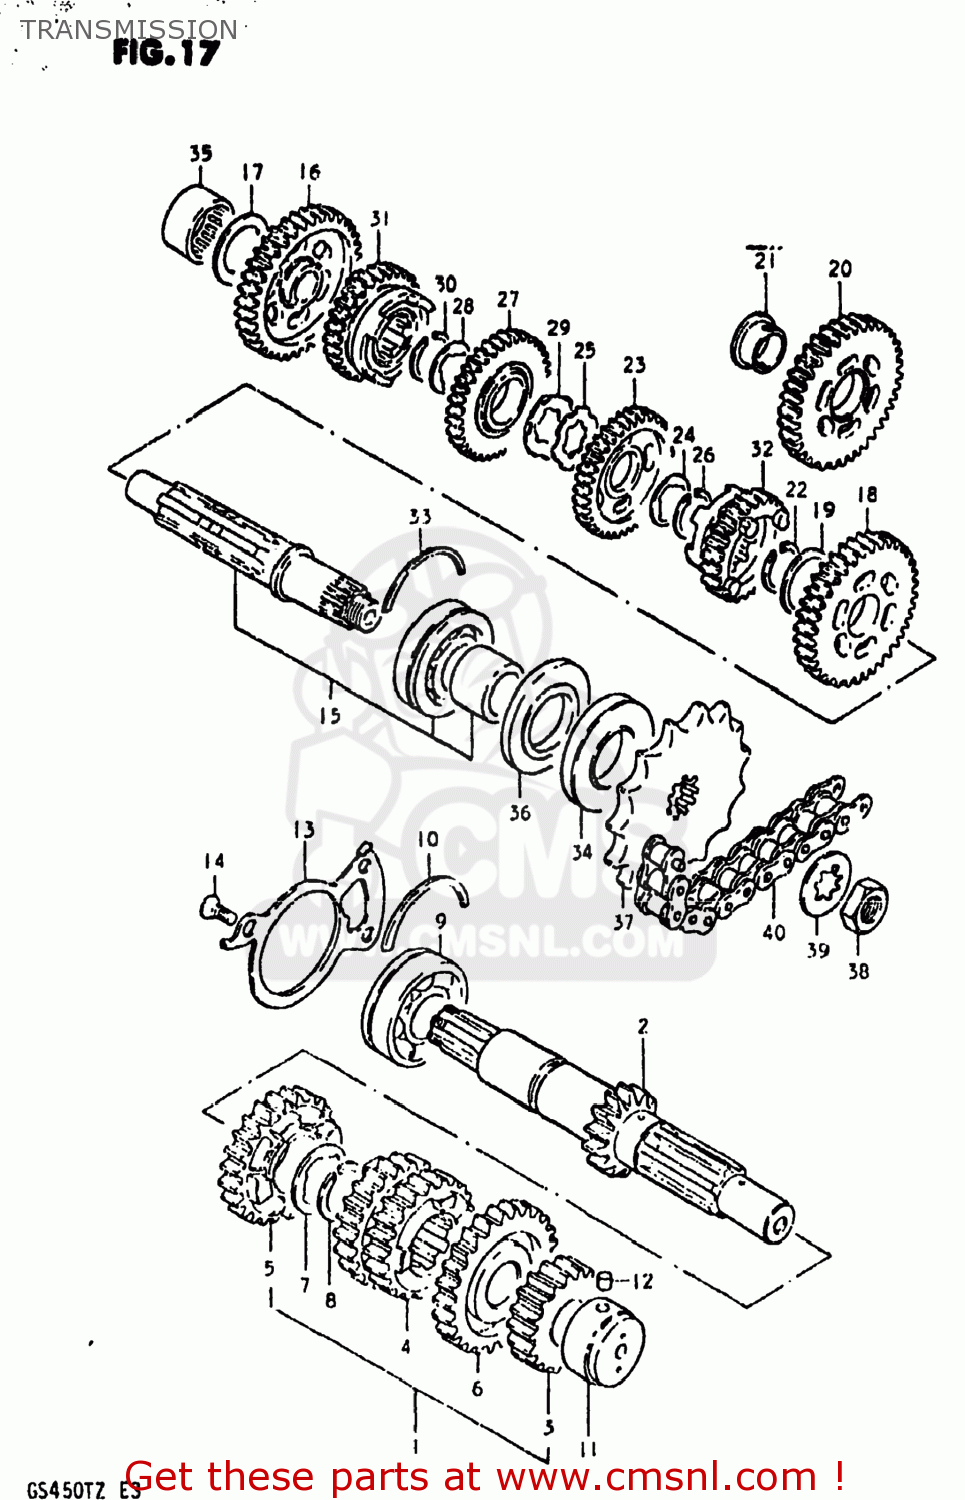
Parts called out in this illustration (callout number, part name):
1	SHAFT,COUNTER
2	SHAFT,COUNTER
3	GEAR,2ND DRIVE(NT:18)
4	GEAR,THIRD DRIVE
5	GEAR,FIFTH DRIVE
6	GEAR,SIXTH DRIVE
7	WASHER
8	CIRCLIP
9	BEARING(25X62X17)
10	C-RING
11	ROLLER BEARING (20X34X2
12	PIN
13	PLATE,COUNTERSHAFT BEARING
14	SCREW
15	SHAFT,DRIVE
16	GEAR,FIRST DRIVEN
17	WASHER
18	GEAR,SECOND DRIVEN
19	WASHER
20	GEAR,SECOND DRIVEN
21	BUSHING
22	CIRCLIP
23	GEAR,THIRD DRIVEN
24	WASHER,LOCK
25	WASHER,LOCK
26	CIRCLIP
27	GEAR,FOURTH DRIVEN
28	WASHER,LOCK
29	WASHER
30	CIRCLIP
31	GEAR,5TH DRIVEN(NT:25)
32	GEAR,SIXTH DRIVEN
33	C-RING
34	SEAL,OIL(32X62X7)
35	ROLLER BEARING (20X34X1
36	SEAL,OIL(32X62X5.5)
37	SPROCKET,ENGINE(NT:16)
38	NUT
39	WASHER
40	CHAIN ASSEMBLY,DRIVE
